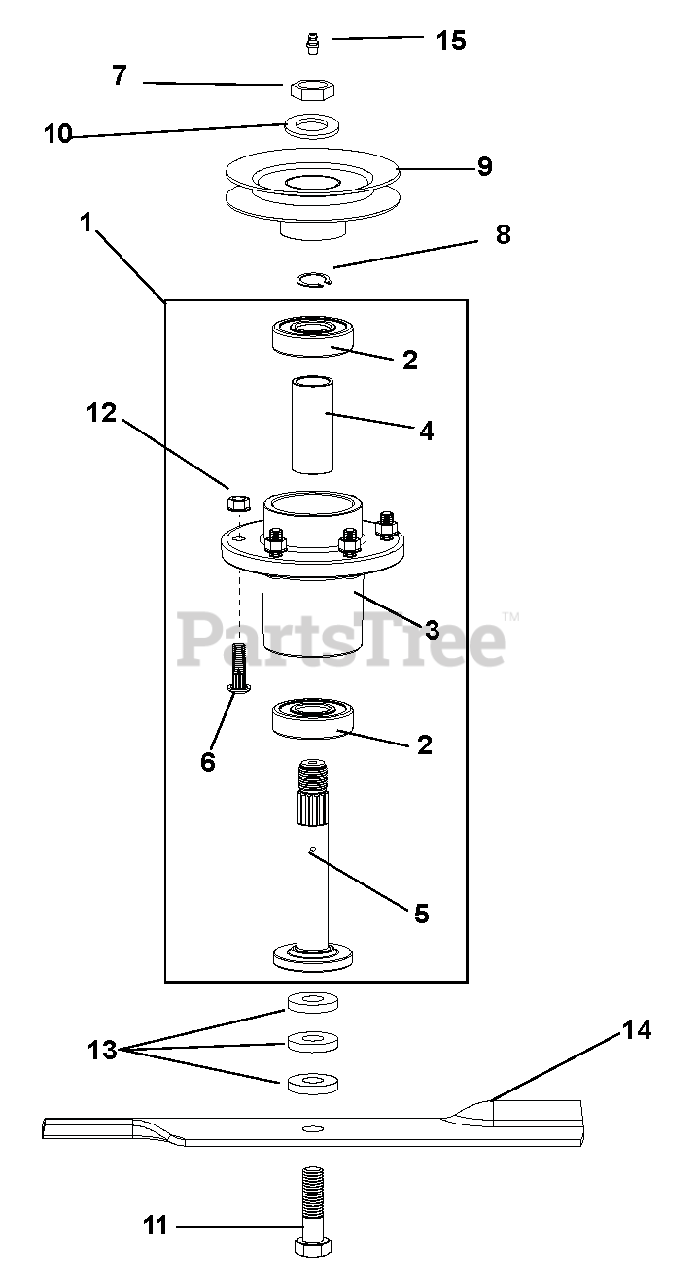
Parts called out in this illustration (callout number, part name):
1	ASSY, SPINDLE S/O
2	BALL BEARING
3	HOUSING
4	SPACER, 1.000 X 1.250 X 2.772
5	SHAFT, SPINDLE 3/4-16
6	BOLT, 3/8-16 X 1.25 RIB
7	LOCKNUT, 3/4-16 CROWN PL
8	RING RETAINER S/O
9	Pulley, Cutter Housing
10	WASHER, .75X1.3125X.120
11	BOLT, 5/8-11 X 2.00 HEX 8 Y
12	@NUT-HEX .31-18 YWZC
13	SPACER, BLADE BOLT
14	18.0" BLADE, 52" DECK
15	FTG, 1/4-28 STRGT GREASE ZERK
